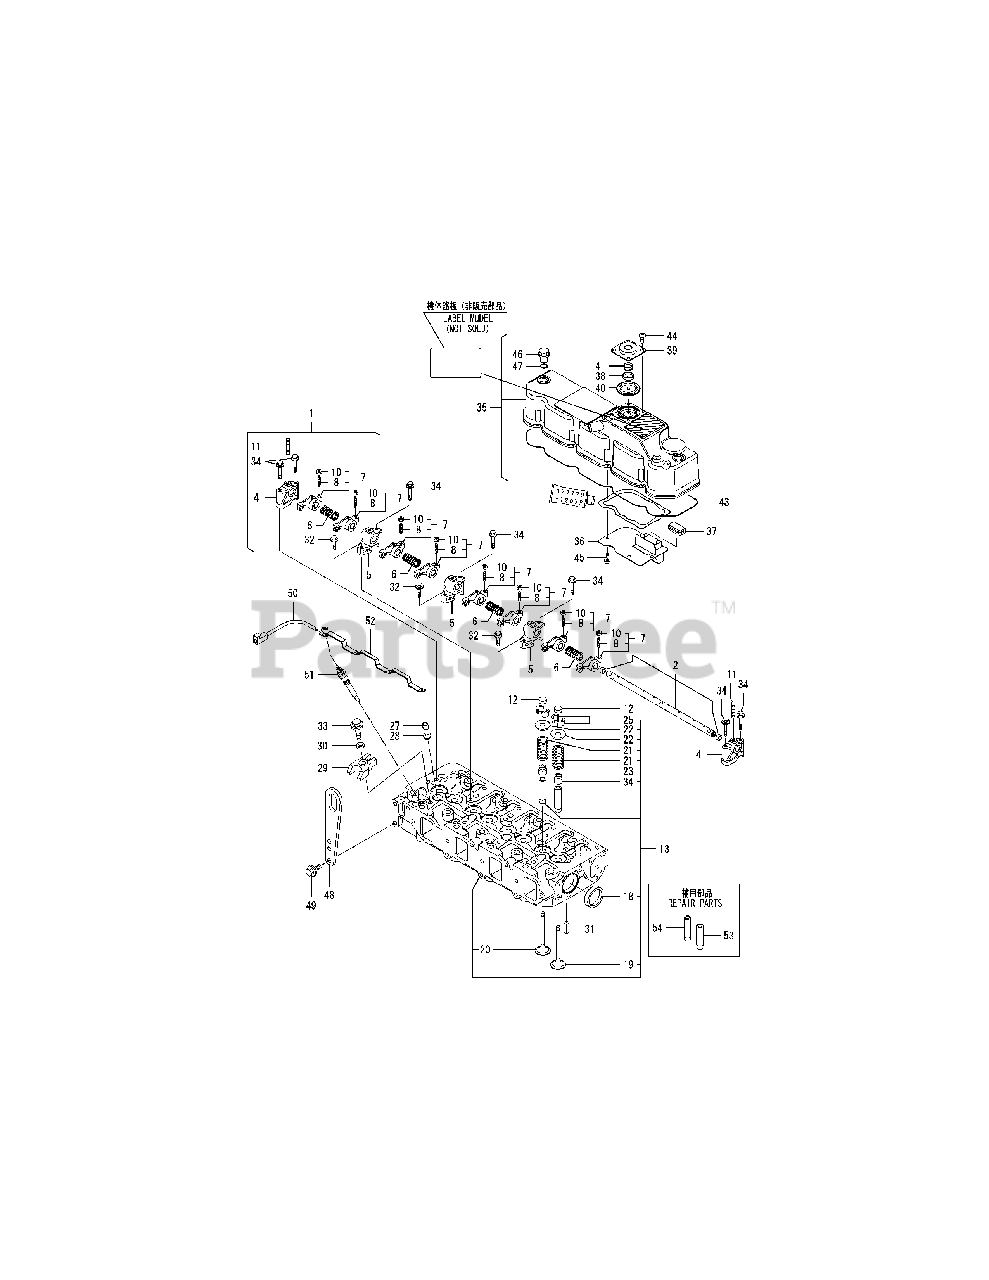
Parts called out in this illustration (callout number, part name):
1	SHAFT ASSY, ROCKER
2	SHAFT, ROCKER ARM
4	SUPPORT, ARM A
5	SUPPORT, ARM B
7	ARM KIT, ROCKER
8	SCREW, VALVE ADJUST
11	STUD M 8X 18 PLATED
13	HEAD ASSY, CYLINDER
20	VALVE, EXHAUST
22	RETAINER, SPRING
23	SEAL, VALVE STEM
24	SEAL, VALVE STEM
27	PROTECTOR, NOZZLE
29	RETAINER, NOZZLE
30	WASHER, INJECTOR
31	SPRING PIN 6X12
32	BOLT M 8X 25 PLATED
33	BOLT M 8X 35 PLATED
34	BOLT M 8X 50 PLATED
37	BAFFLE, BREATHER
39	COVER, DIAPHRAGM
41	SPRING, DIAPHRAGM
43	GASKET, BONNET
47	O-RING 1A P-12.0
48	LIFTER, ENGINE
49	BOLT M 8X 16 PLATED
50	HARNESS, GLOW PLUG
52	CONNECTOR, GLOW PLUG
54	GUIDE, EXHAUST VALVE
